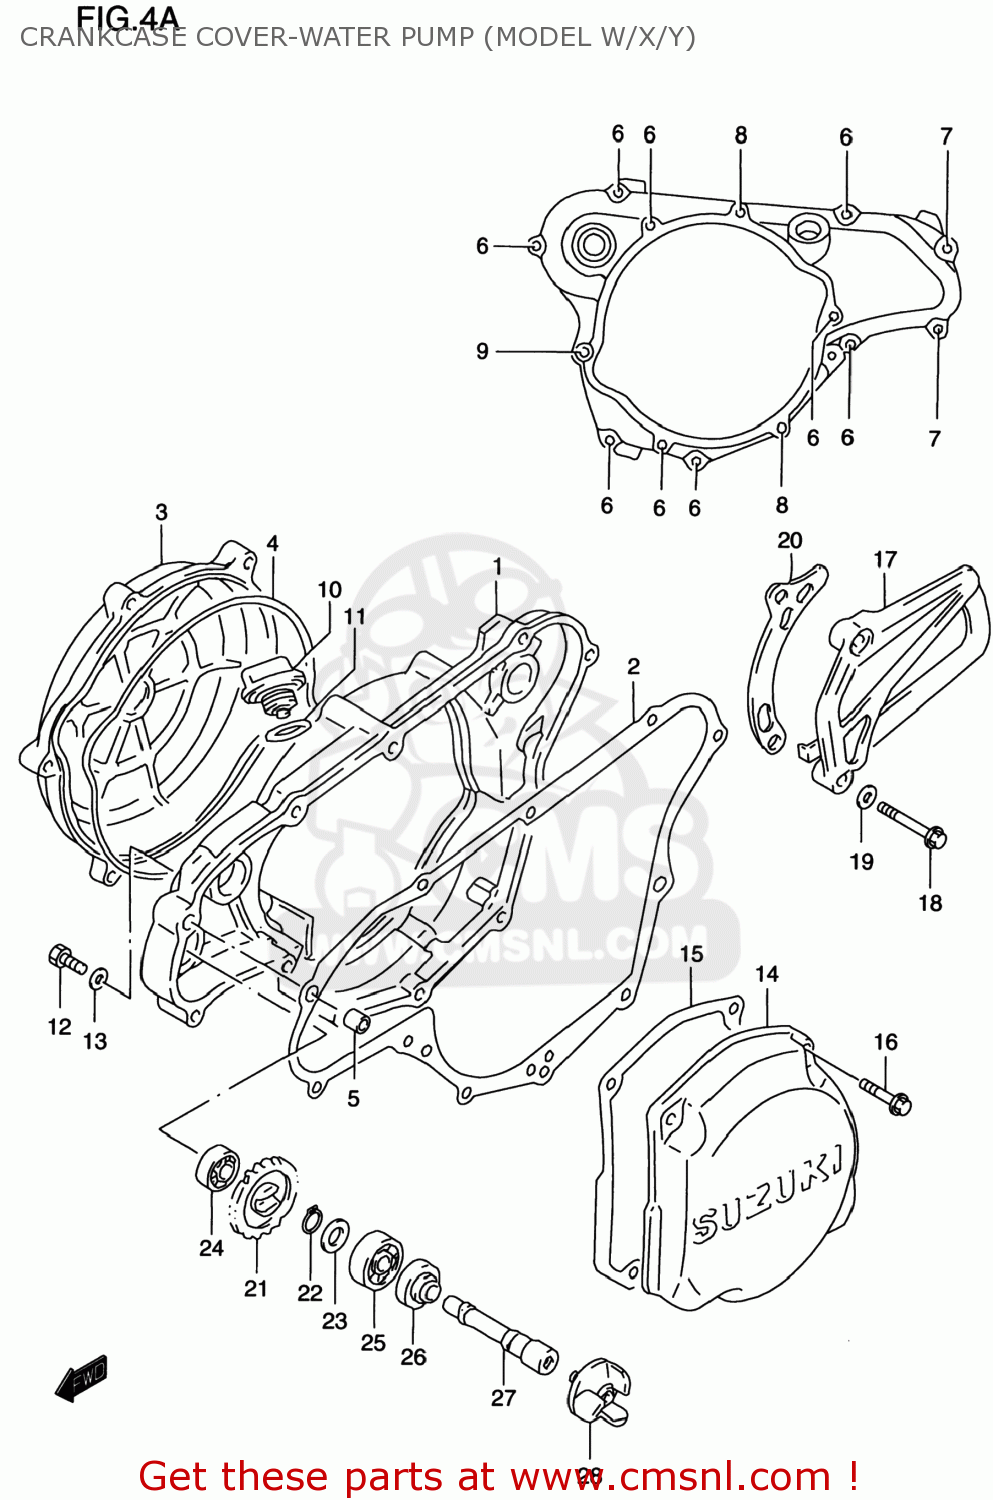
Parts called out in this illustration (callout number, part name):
1	COVER,CLUTCH
2	GASKET,CLUTCH COVER
3	COVER,CLUTCH,OUTER
4	O RING,CLUTCH COVER OUTER
5	PIN
6	SCREW
7	BOLT,G/S SWITC
8	BOLT
9	BOLT
10	PLUG,OIL FILLER
11	O RING(D:3.1,ID:16.8)
12	SCREW(6X10)
13	GASKET(6.2X11X1).2 (NAS)
14	COVER,MAGNETO
15	GASKET,MAGNETO COVER
16	SCREW
17	COVER,ENGINE SPROCKET
18	BOLT,G/S SWITC
19	WASHER(6.5X14X2)
20	PLATE,FR CHAIN GUIDE
21	GEAR,WATER PUMP DRIVEN
22	CIRCLIP,10MM
23	SHIM(10X14X1)
24	BEARING(8X22X7)
25	BEARING(10X26X8)
26	SEAL,WATER PUMP OIL
27	SHAFT,WATER PUMP
28	IMPELLER,WATER PUMP
